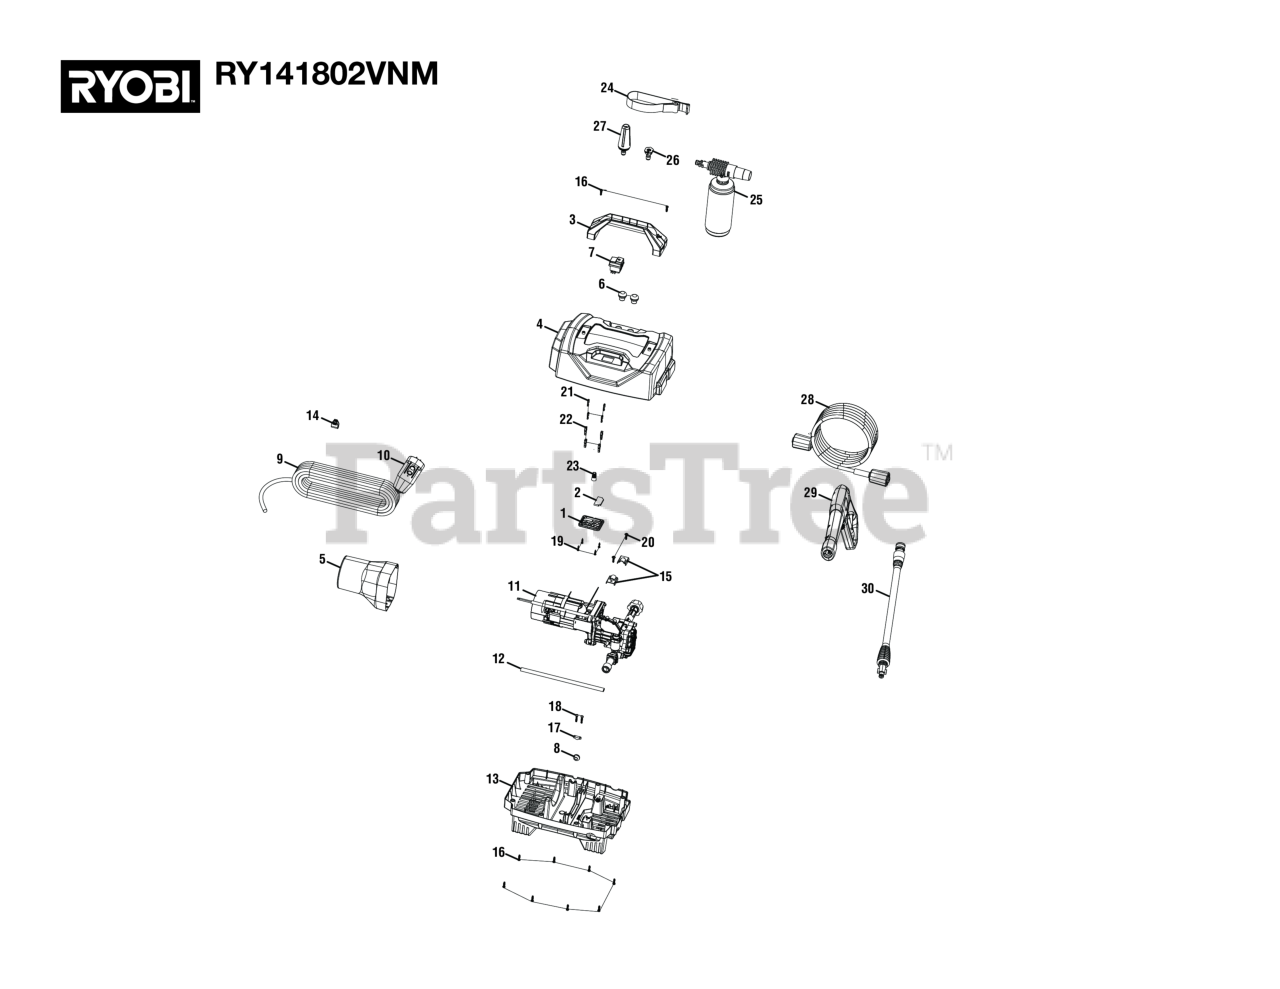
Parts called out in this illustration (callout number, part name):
1	Switch Cover
3	Plastic Handle
4	Upper Housing
5	Air Shourd
6	Nozzle Grommet
7	On/Off Switch
8	Housing Rubber Grommet
9	Electrical Cord
10	GFCI Plug 2 Prong
11	Pump Motor
12	Terminal Sleeve
13	Lower Housing
14	Electric Cord Clip
15	Motor Clamp Plate
16	Screw (M4.2 x 15 mm, Phillips Hd. S.T.)
17	Cord Clamp
18	Screw (M3.5 x 20 mm, Button Hd.)
19	Screw (M2.9 x 14 mm, Pan Hd.)
20	Screw w/ Washer (M4 x 16 mm, Round Hd.)
21	Tinned Brass (Terminal)
22	Plastic Sleeve (Terminal)
23	Tuerca para alambre
24	Hose Storage Strap (Velcro)
25	Foam Nozzle
26	Nozzle (15 deg)
27	Turbo Nozzle
28	20ft Hose
29	Trigger Handle Assembly
30	Spray Wand Assembly
